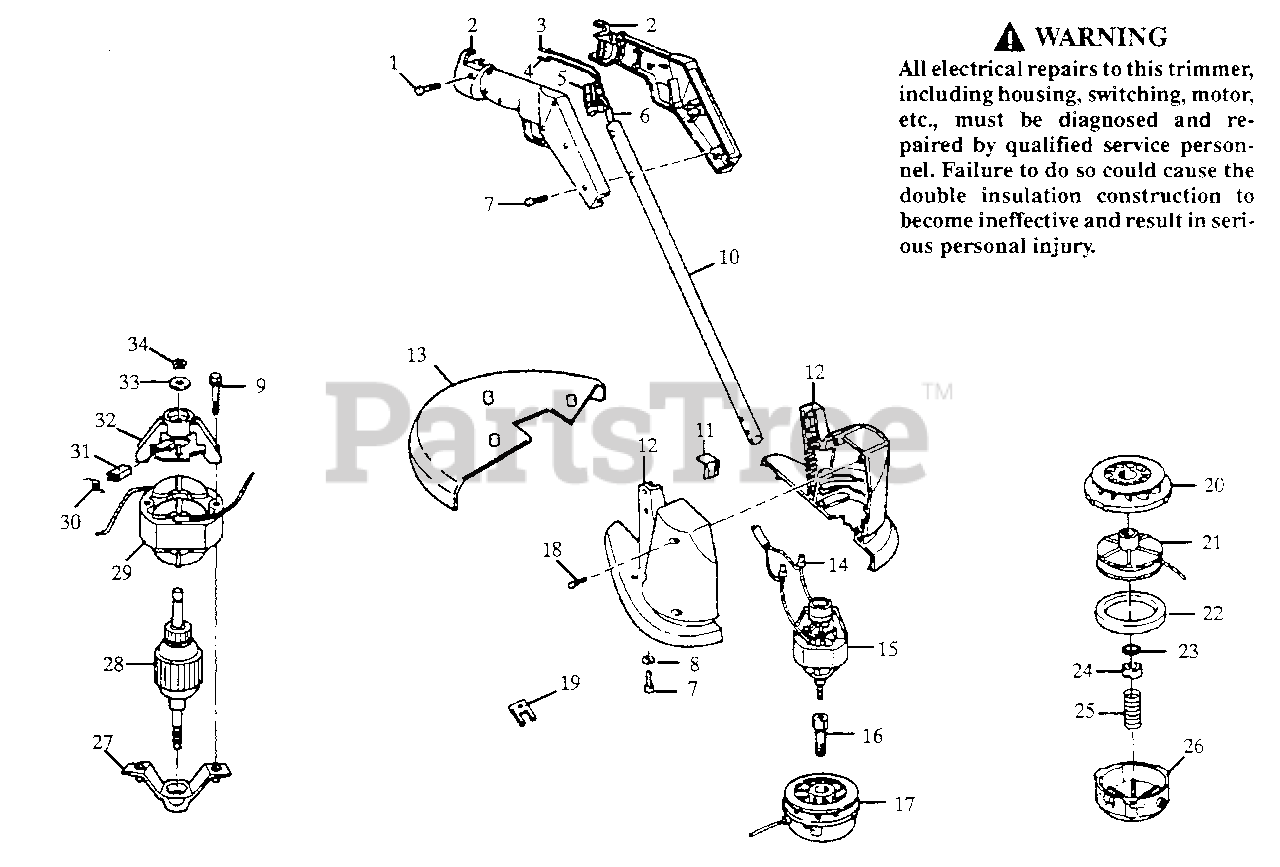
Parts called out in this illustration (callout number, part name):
2	Handle Set
3	Wire Blade Ass'y.
4	Wire Blade Ass'y.
5	Trigger Switch
11	Line Cutter
12	Housing Set
14	Terminal Cap
15	Motor Ass'y.
16	Shaft Adapter
17	Cutting Head Ass'y.
19	Spanner Wrench
20	Rear Plate/Baffle Ass'y.
21	Spool w/Line
22	Foam Pad
24	Adapter Nut
26	Hub Ass'y.
27	Endbell Ass'y.
28	Armature Ass'y.
29	Field Ass'y.
30	Brush Spring
31	Carbon Brush
32	Bracket/Plate Ass'y.
33	Washer, Shim
34	Retaining Ring
